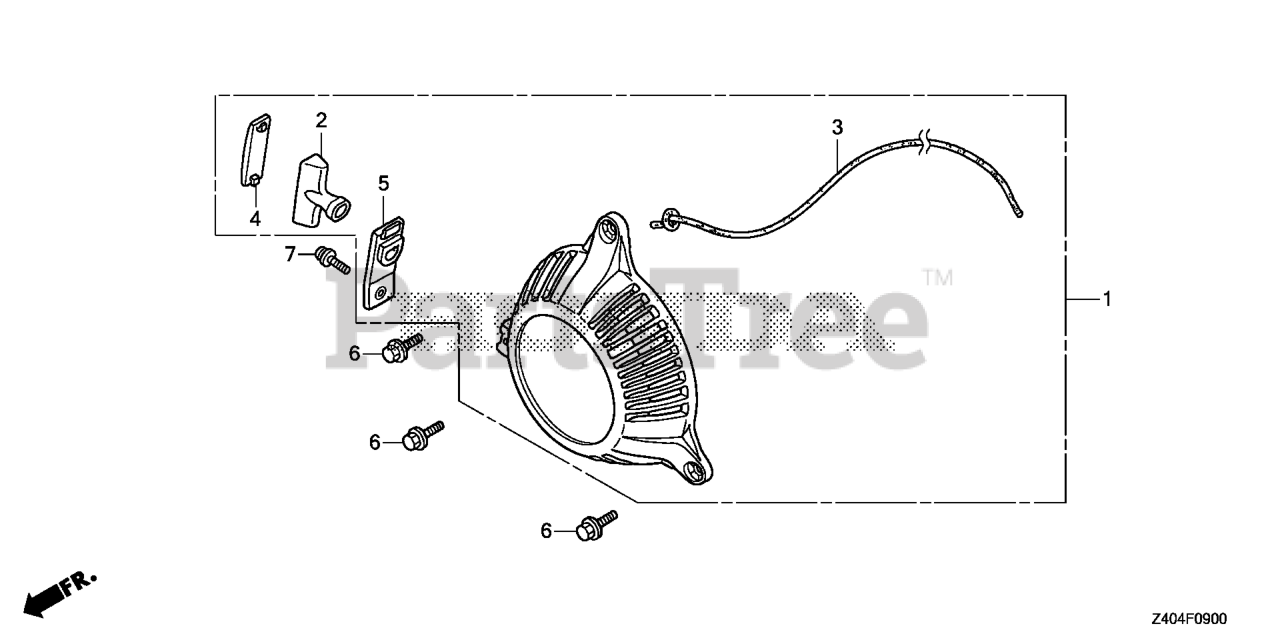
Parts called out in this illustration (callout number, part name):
1	STARTER ASSY., RECOIL
2	GRIP, STARTER
3	ROPE, RECOIL STARTER
4	COVER, GRIP
5	GUIDE, STARTER ROPE
6	BOLT, FLANGE (5X10)
7	SCREW-WASHER (5X10)
